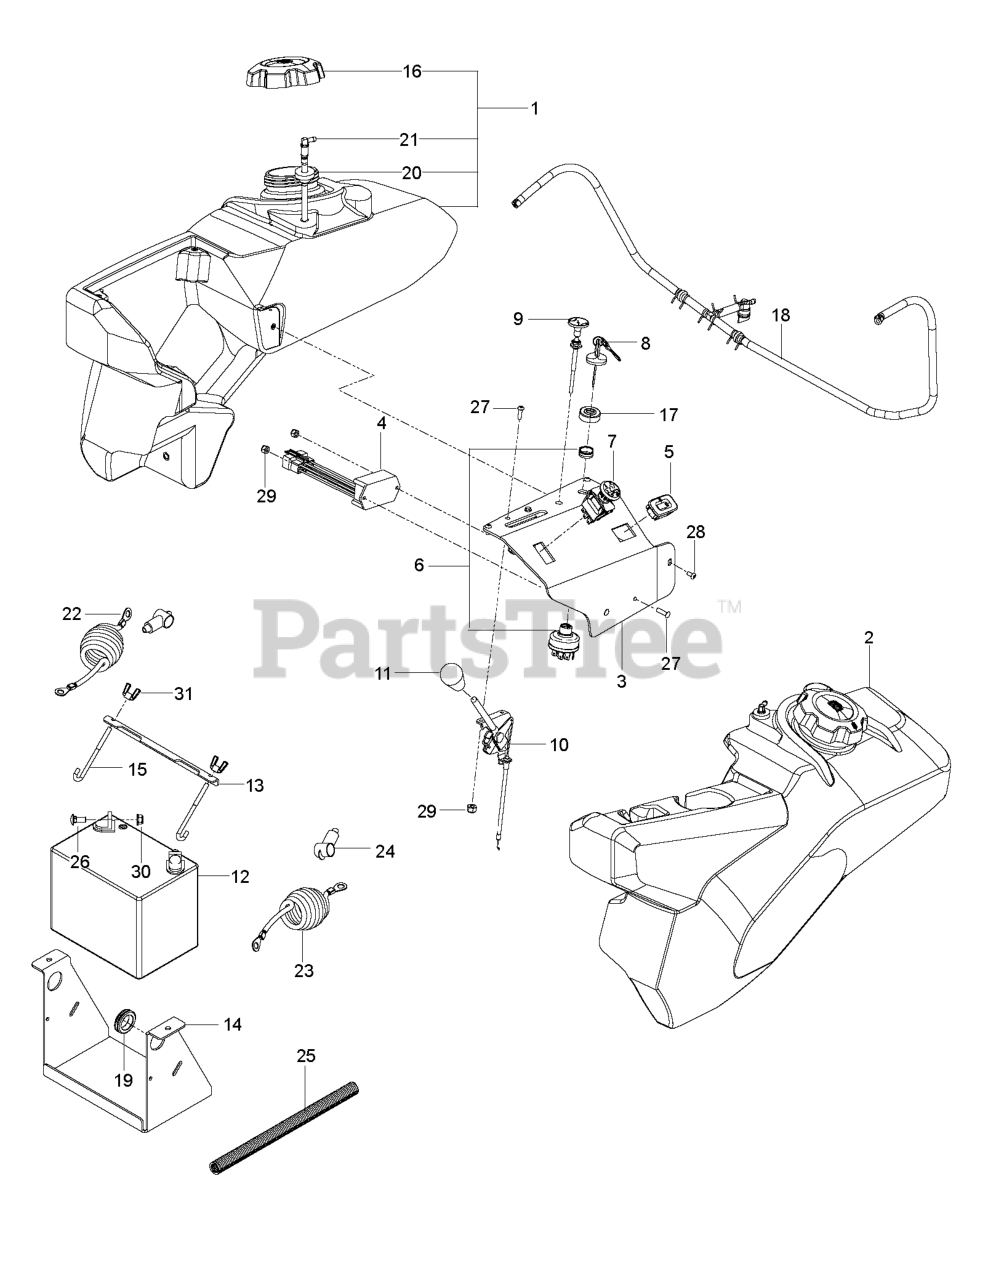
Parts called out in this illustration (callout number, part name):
1	FUEL TANK ASM RT
2	RUBBER GROMMET
2	FUEL TANK ASM LT
3	PANEL.CONTROL.GAS.GRAY
4	TIMER, SEAT
5	HOUR METER
6	SWITCH, IGNITION, INDAK
7	SWITCH, PTO 10 AMP
8	KEY, IGNITION
9	CABLE, CHOKE, 48"
10	CABLE, THROTTLE, 60"
11	KNOB - SHIFT
12	BATTERY, 12 V 330 AMP
13	BRACKET, BATTERY MOUNT
14	BRACKET, BATTERY, BLK
16	FUEL CAP, HTC
17	CAP IGNITION NUT
19	RUBBER GROMMET
20	RUBBER GROMMET
21	FITTING, FUEL
22	CABLE, POSITIVE, 55"
23	CABLE, NEG, 55"
25	LOOM, SPLIT, CONVOLUTED
26	RP BOLT 5/16-18 X3/4 ZN/YEL GR
27	SCR #10-24 X .75 SKT HD BLK
28	SCR #10-24 X 3/8 SKT HD BLK OX
29	NUT 10-24 NYLOC
30	5/16-18 NYLOC FLANGE NUT
31	WING NUT 1/4
